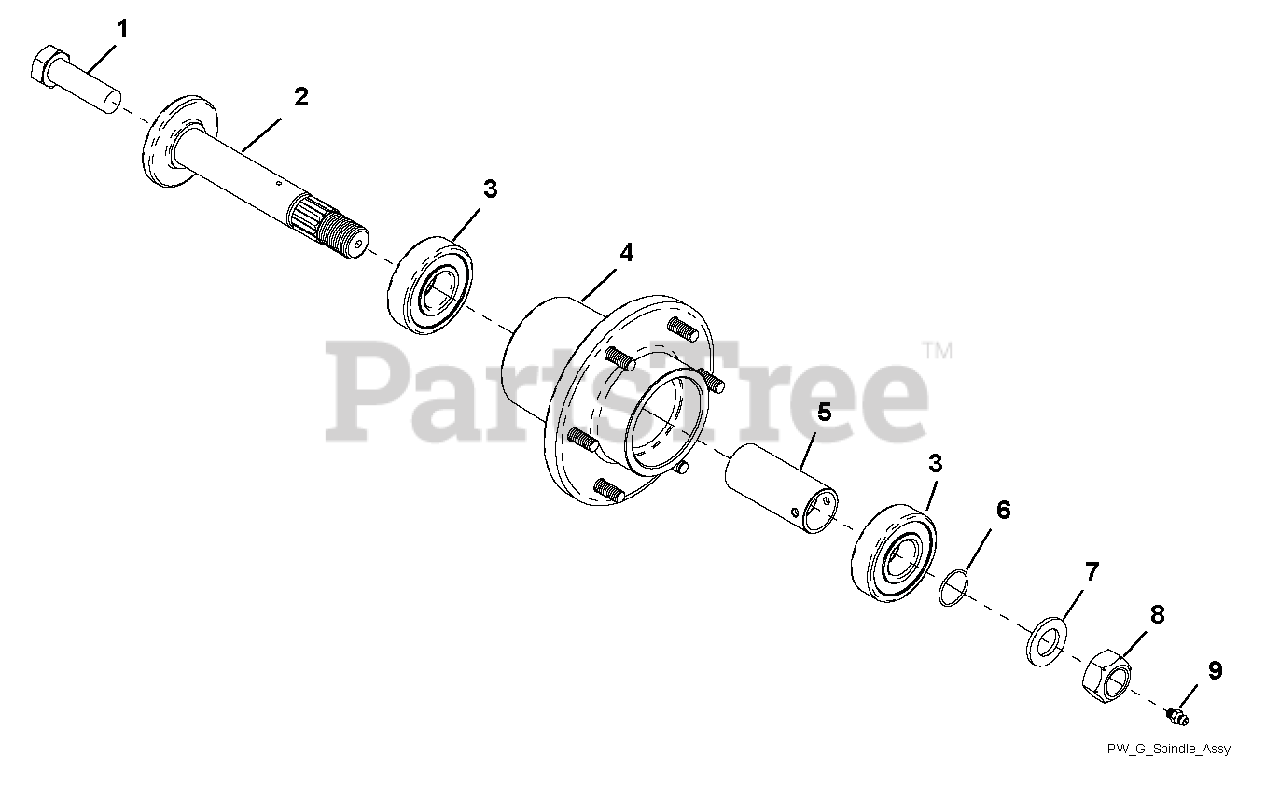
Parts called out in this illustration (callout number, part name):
1	BOLT, 5/8-11 X 2.00 HEX 8 Y
2	SHAFT, SPINDLE 3/4-16
3	BEARING, 6305LLC
4	HOUSING, SPINDLE W/STUDS
5	SPACER, 1.250X1.000X2.780
6	RING RETAINER S/O
7	WASHER, .75X1.3125X.120
8	LOCKNUT, 3/4-16 CROWN PL
9	FTG, 1/4-28 STRGT GREASE ZERK
